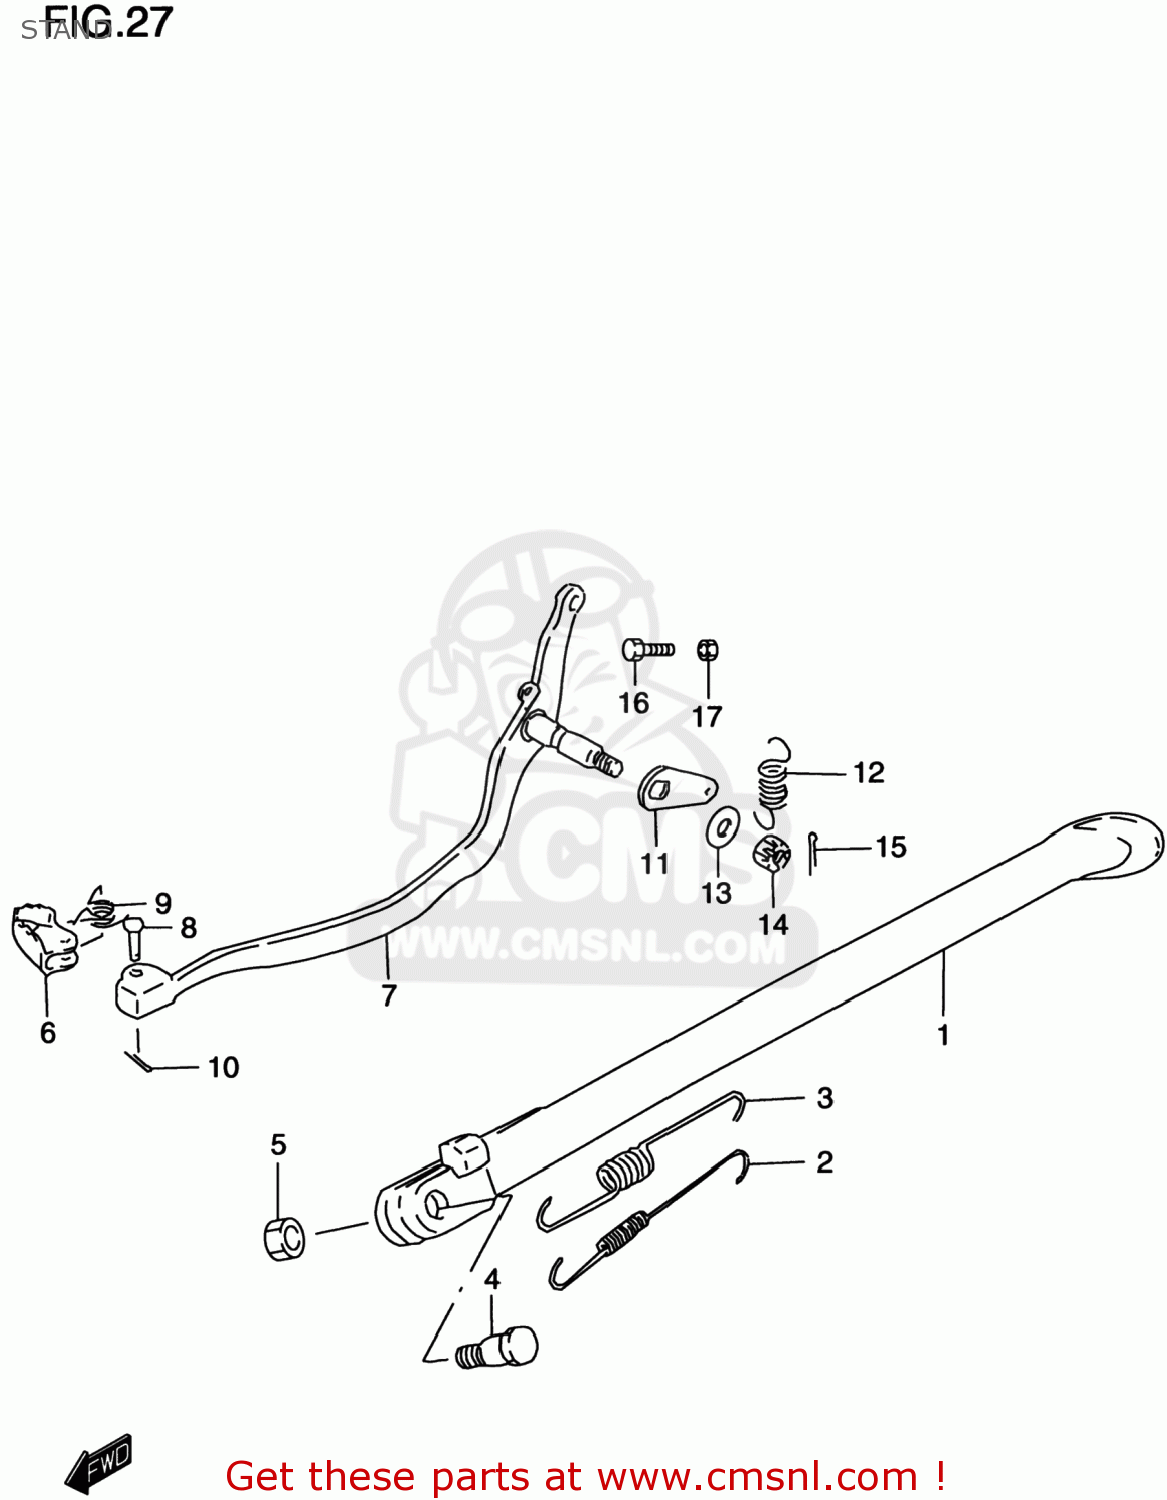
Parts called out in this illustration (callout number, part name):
1	STAND COMP,PROP
2	SPRING
3	SPRING
4	BOLT L:30
5	NUT
6	PEDAL,BRAKE
7	ARM,BRAKE PEDAL
8	PIN
9	SPRING
10	PIN
11	ARM,BRAKE RETURN SPRING
12	SPRING
13	WASHER
14	NUT
15	PIN 20X20
16	BOLT(6X23)
17	NUT 6MM
